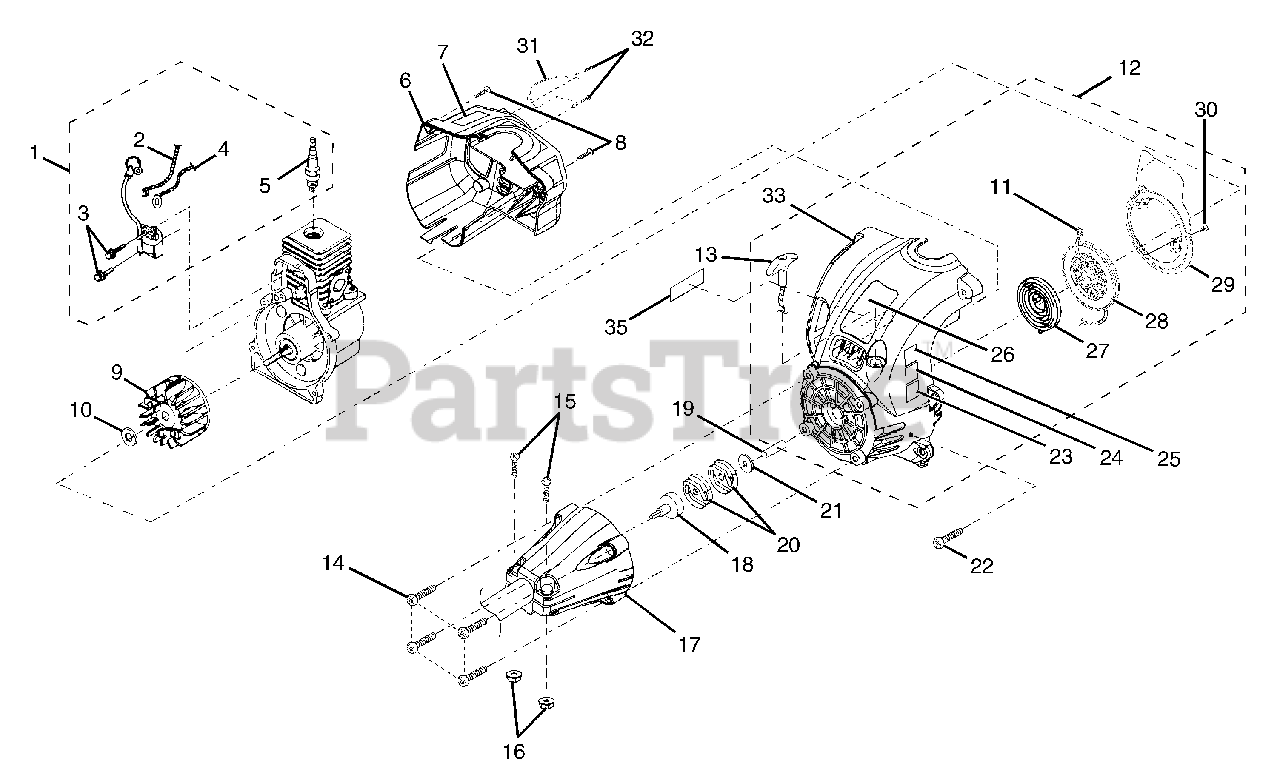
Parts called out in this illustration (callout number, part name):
1	IGNITION KIT
2	ELECTRICAL LEAD
4	ELECTRICAL LEAD
5	SPARK PLUG
6	REAR COVER
7	LOGO PLATE
8	SCREW (10-14 x 7/8)
9	ROTOR AND PAWL ASSEMBLY
11	STARTER ROPE 42 in.
12	STARTER ASSEMBLY
13	ERGO GRIP
17	NOSE CONE ADAPTER
18	DRUM & CONNECTOR
20	CLUTCH DISK (ST185 & ST385)
21	WASHER
23	DECAL, 112 POWER SOUND
24	DECAL, CE
25	DECAL, ZIP START
26	DECAL, MODEL
27	SPRING & CONTAINER
28	STARTER PULLEY
29	AIR BAFFEL PLATE
31	MUFFLER GUARD
33	STARTER HOUSING & EYELET
35	FUEL MIX RATIO DECAL
